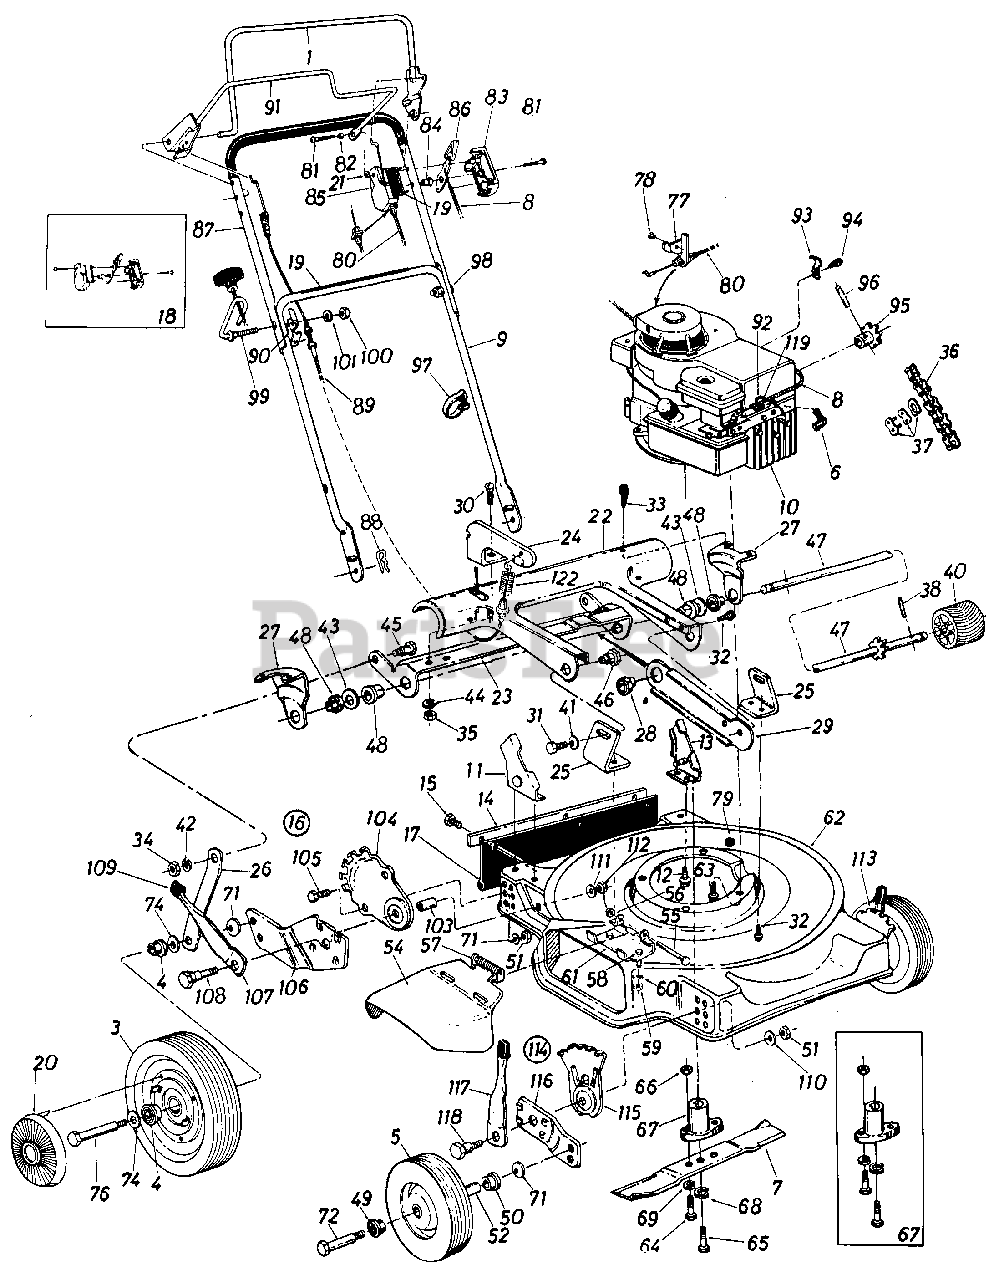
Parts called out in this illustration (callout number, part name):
1	Control Handle Ass'y.-L.H.
3	Rear Wheel Ass'y. Comp. 9 x 1.75
4	Flange Brg. 1/2" I.D.
5	Front Wheel Ass'y. Comp.
6	Spark Plug Boot
7	Blade 22"
8	Throttle Wire 53.0"
9	Lower Handle
10	Engine
11	Handle Brkt. Ass'y. R.H.
12	Hex Wash. Hd. "B"-Tap Scr. 5/16-18 x .50" Lg.
13	Handle Brkt. Ass'y. L.H.
14	Retainer Strip
15	Hex AB-Tap Scr. 1/4 x .62" Lg.
16	R.H. Height Adj. Comp.
17	Rear Flap Ass'y.
18	Kit Control Housing Comp.
19	Control Labels
21	Flat Wash. .203" I.D. x .406" O.D.
22	Pinion Pivot Cover 22"
24	Engagement Arm
25	Pivot Brkt.
27	Axle Brkt.
28	Flanged Ball Brg. .500" I.D.
29	Brg. Support
30	Carriage Bolt 1/4-20 x .50" Lg .*
31	Hex Bolt 3/8-16 x .50" Lg.*
32	Hex "B"-Tap Scr. 1/4" x .38" Lg.
33	Hex Wash. Hd. "AB"-Tap Scr. 1/4" x .62" Lg.
34	Hex Nut 5/16-18 Thd.*
35	Hex Nut 1/4-20 Thd.*
36	#48 Chain 1/2" Pitch 49 Links
37	#48 Master Link
38	Spring Pin Spir. 3/16" Dia. x 1.25" Lg.
40	Drive Pinion
41	Bell-Wash. .400" I.D. x .88" O.D. x .060
42	L-Wash. 5/16" I.D.*
43	Fl-Wash. .531" I.D. x .930" O.D. x .050
44	L-Wash. 1/4' I.D.*
45	Shld. Bolt .437" Dia. x .162
46	Shld. Nut .625" Dia. x .162
47	Pinion Shaft w/ 7 Tooth Sprocket
48	Flange Brg. .506" I.D.
49	Bearing 3/8" I.D.
50	Bearing 1/2" I.D.
51	Hex Nut 3/8-16 Thd.*
54	Chute Deflector Ass'y. Comp.
56	Cap Speed Nut 1/4" Rod
57	Torsion Spring
58	Hex Bolt 1/4-20 x .50" Lg.*
59	Hex Nut 1/4-20 Thd.*
60	L-Wash. 1/4" I.D.*
61	Hinge Plate
62	22" Deck Ass'y.
63	Hex Wash. Hd. TT-Tap Scr. 3/8-16 x 1.0" Lg.
64	Hex Bolt 5/16-24 x 1.00" Lg. (Grade 5)
65	Hex Bolt 3/8-24 x 2.25" Lg. (Grade 5)
66	Hex Nut 5/16-24 Thd.
67	Blade Adapter Kit
68	L-Wash. 3/8" I.D. H.D.
69	L-Wash. 5/16" I.D.*
71	Bell-Wash..40" I.D.
72	Front Axle Bolt
74	Fl-Wash. .531" I.D. x .93"
76	Rear Axle Bolt
77	Cable Bracket
78	Pop Rivet .156" Dia. x .379
80	Control Cable 39.0"
81	Truss Mach. Self-Tap Scr. #12 x 1.50" Lg.
82	Spacer.23" I.D.
83	Control Panel Half
84	Control Disc Pin
85	Clutch Panel Half
86	Throttle Control Lever
87	Upper Handle
88	Hairpin Cotter
89	Clutch Cable w/ Spring
90	Cable Mtg. Brkt.
91	Drive Control Handle
92	Casing Clamp
93	Casing Clamp
94	Hex "B"-Tap Scr. #10 x .38"
95	10 Tooth Sprocket Ass'y.
96	Spiral Pin 3/16" Dia. x 1.00"
98	Curved Hd. Carriage Bolt 5/16-18 x 1.38" Lg.
99	Rope Guide Bolt
100	Hex Nut 5/16-18 Thd.*
101	L-Wash. 5/16" I.D.*
103	Spacer .395" I.D. x .503" O.D. x .562" Lg.
104	Index Plate
105	Hex Bolt 3/8-16 x .75" Lg.*
106	Pivot Bar R.H.
107	Spring Lever
108	Shoulder Bolt .500" Dia. x 3.75" Lg.
109	Spring Lever Knob
110	Bell-Wash. .39 I.D. x 1.4 O.D.
111	Bell-Wash. .336" I.D. x .860 O.D.
112	Hex L-Nut 5/16-18 Thd.
113	Height Adj. Ass'y. Comp. L.H.
114	Height Adj. Ass'y. Comp. R.H.
115	Height Adj. Plate
116	Pivot Bar
117	Spring Lever Ass'y. w/ Knob
118	Shoulder Bolt .500" Dia. x .375" Lg.
119	Hex Wash. Hd. AB-Tap Scr. #8 x .38" Lg.
122	Compression Spring .47" O.D. x 1.93" Lg.
8222-190-5	Hardware Pack
